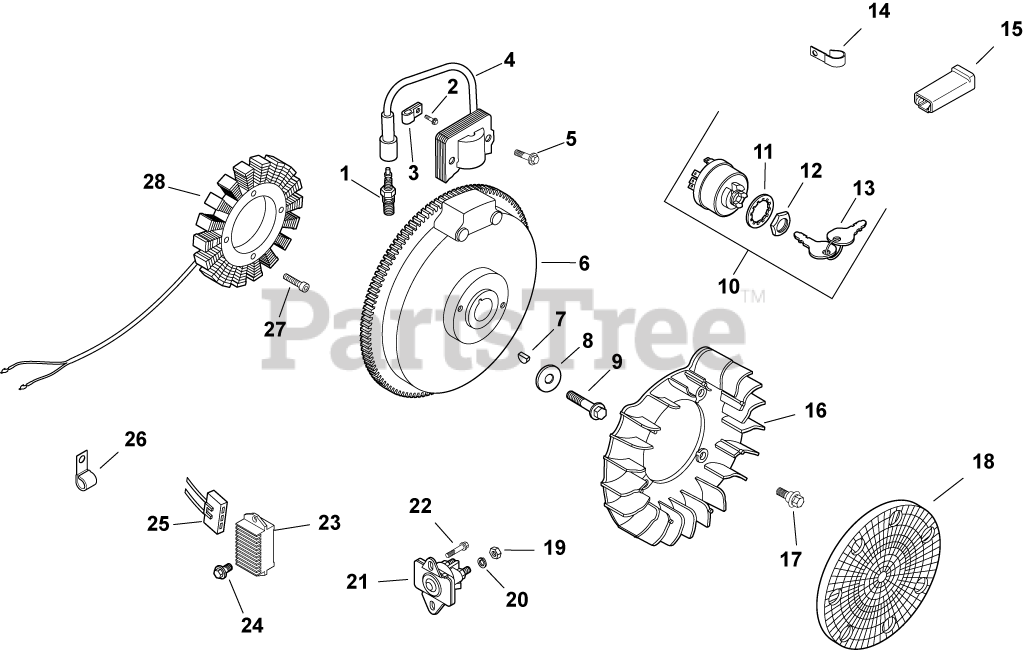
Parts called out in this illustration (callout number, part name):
1	PLUG, SPARK (STD)
2	SCREW, FLG THD FRM M5X.8X10
4	MODULE, IGNITION
5	SCREW, FLG THD FRM M5X.8X20-(#25086399S)
7	KEY, 3/16" X 5/8"
8	WASHER, FLAT 13/32"
9	SCREW, FLG M10X1.5X45 - (#25086361S)
10	SWITCH ASSY, KEY (KM)-USE 25 099 32-S
11	WASHER, INTERNAL TOOTH
12	NUT, KEY SWITCH
13	KEY, SET -USE 48 340 01-S
14	CLIP, CABLE
15	CONNECTOR (1 CONTACT)
16	FAN - DISCONTINUED
17	BOLT, SHOULDER
19	NUT, JAM 1/4-20 GRADE 2
20	WASHER, INT TOOTH LOCK 1/4"
21	SOLENOID - WATERPROOF (KM)-USE 25 435 08
22	SCREW,FLG THD FRM M6X1.0X16-(#25086397S)
23	REG/RECT-15 AMP (KM)-USE 41 403 10-S
24	SCREW, FLG M6X1.0X16
25	CONNECTOR, BODY (KM)-USE 25 155 41-S
26	CLIP, TUBE & WIRING (KM)
27	SCREW, M5X0.8X25 - (#25086402S)
28	KIT, 15 / 20 AMP STATOR
